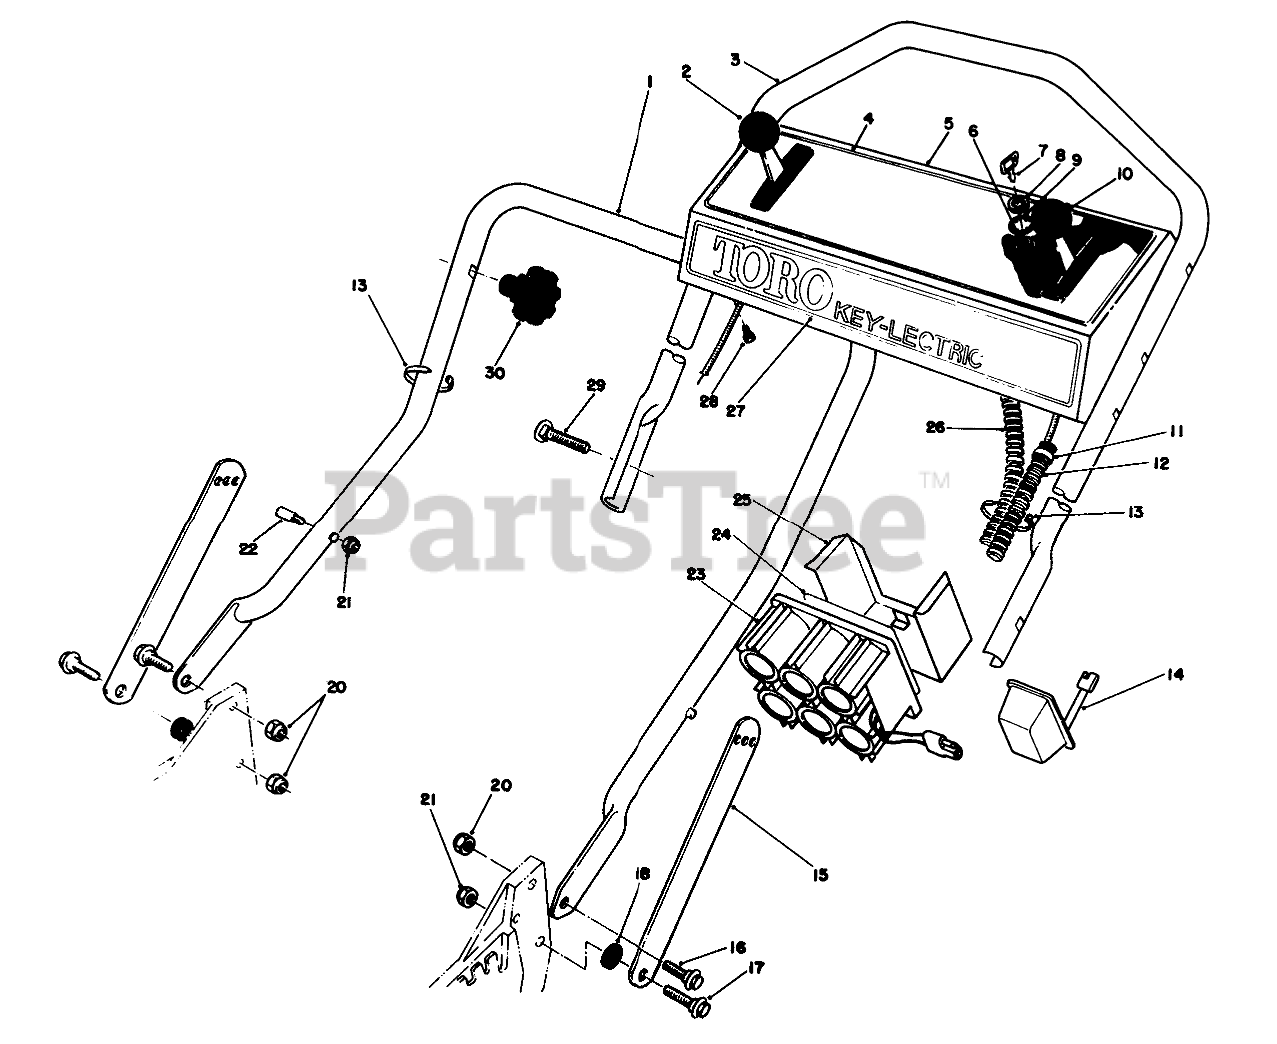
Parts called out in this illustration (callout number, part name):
1	LOWER HANDLE ASM
2	GROUND SPEED CONTROL
3	Handle-Upper
4	DECAL-PANEL INSTR.
5	Panel-Control (Incl. Ref. #4)
6	Switch-Starter (Incl. Ref. #8-9)
7	KEY-IGNITION
8	NUT-HH
9	WASHER-TOOTH, INTERNAL
10	THROTTLE CONT-SERVICE
11	FITTING-RING
12	CONTROL CABLE COVER
13	TIE-CABLE
14	Charger
15	Handle Latch
16	SCREW-SHOULDER
17	SCREW-SHOULDER
18	SPACER
20	NUT-LOCK, NI
21	NUT-LOCK, NI
22	HANDLE PIN
23	BATTERY ASSEMBLY
24	Decal
25	Retainer-Battery
26	WIRE HARNESS
27	Decal-Toro
28	SCREW-HWHTF
29	5/16-18 X 2 HNDLE SCREW
